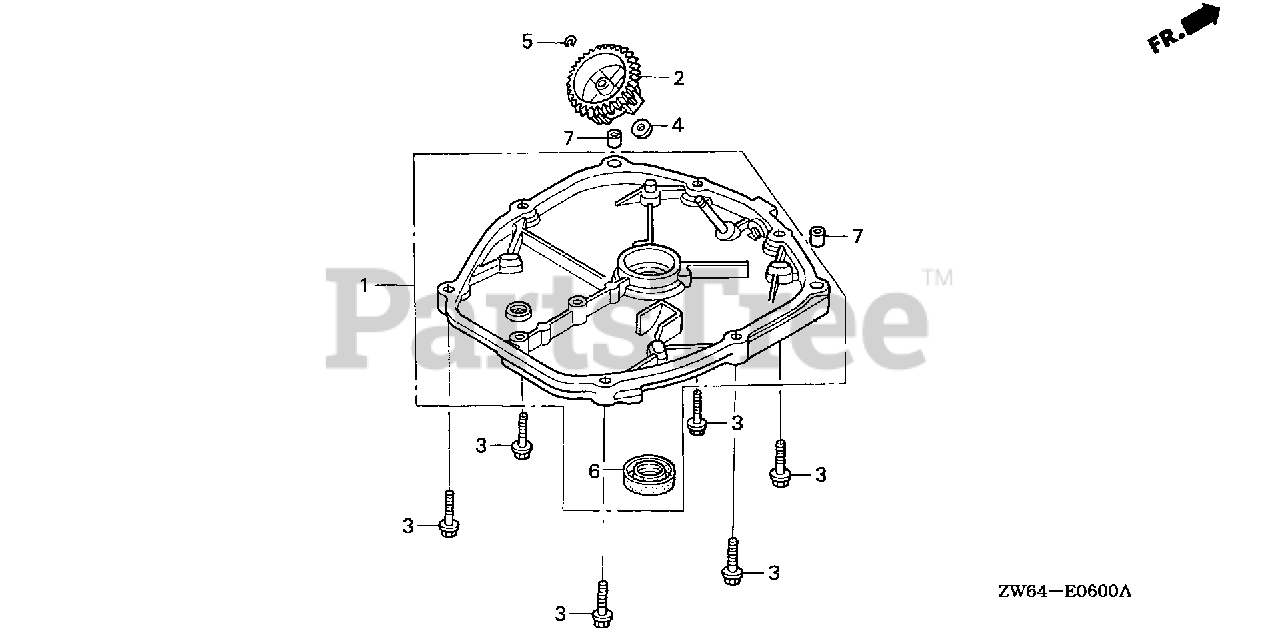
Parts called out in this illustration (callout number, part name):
1	COVER, CRANKCASE SIDE
2	HOLDER, GOVERNOR WEIGHT
3	BOLT, FLANGE (5X23)
4	WASHER (4.2X13)
5	CLIP, GOVERNOR HOLDER
6	OIL SEAL (17X27X5) (KOYO)
7	PIN, DOWEL (6X10)
